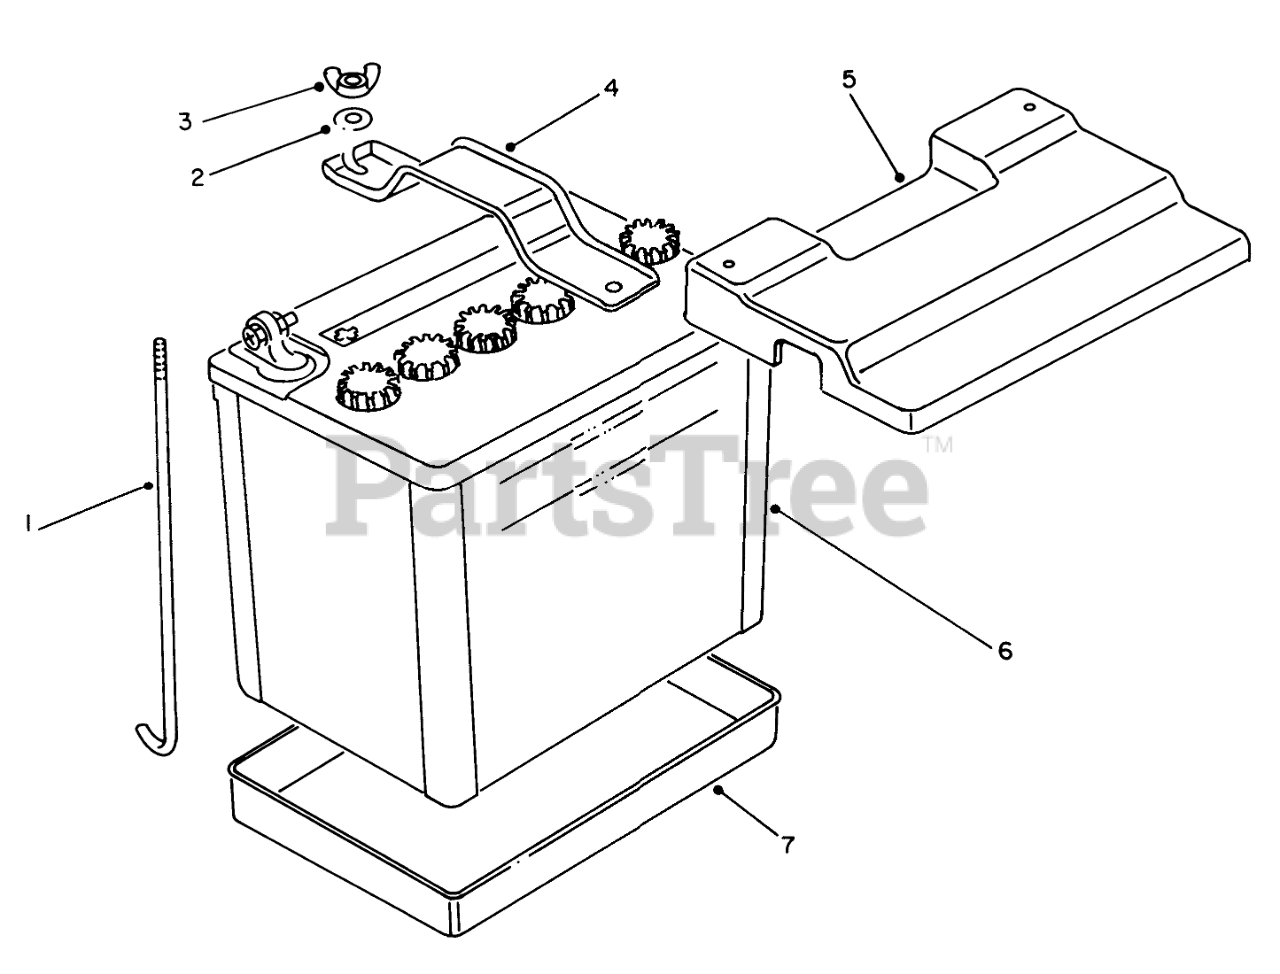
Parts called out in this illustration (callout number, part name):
1	BATT HOLDER BOLT
2	Washer
3	WING NUT
4	BATTERY BAND
5	BATTERY COVER
6	Battery-12V.
7	Tray-Battery
